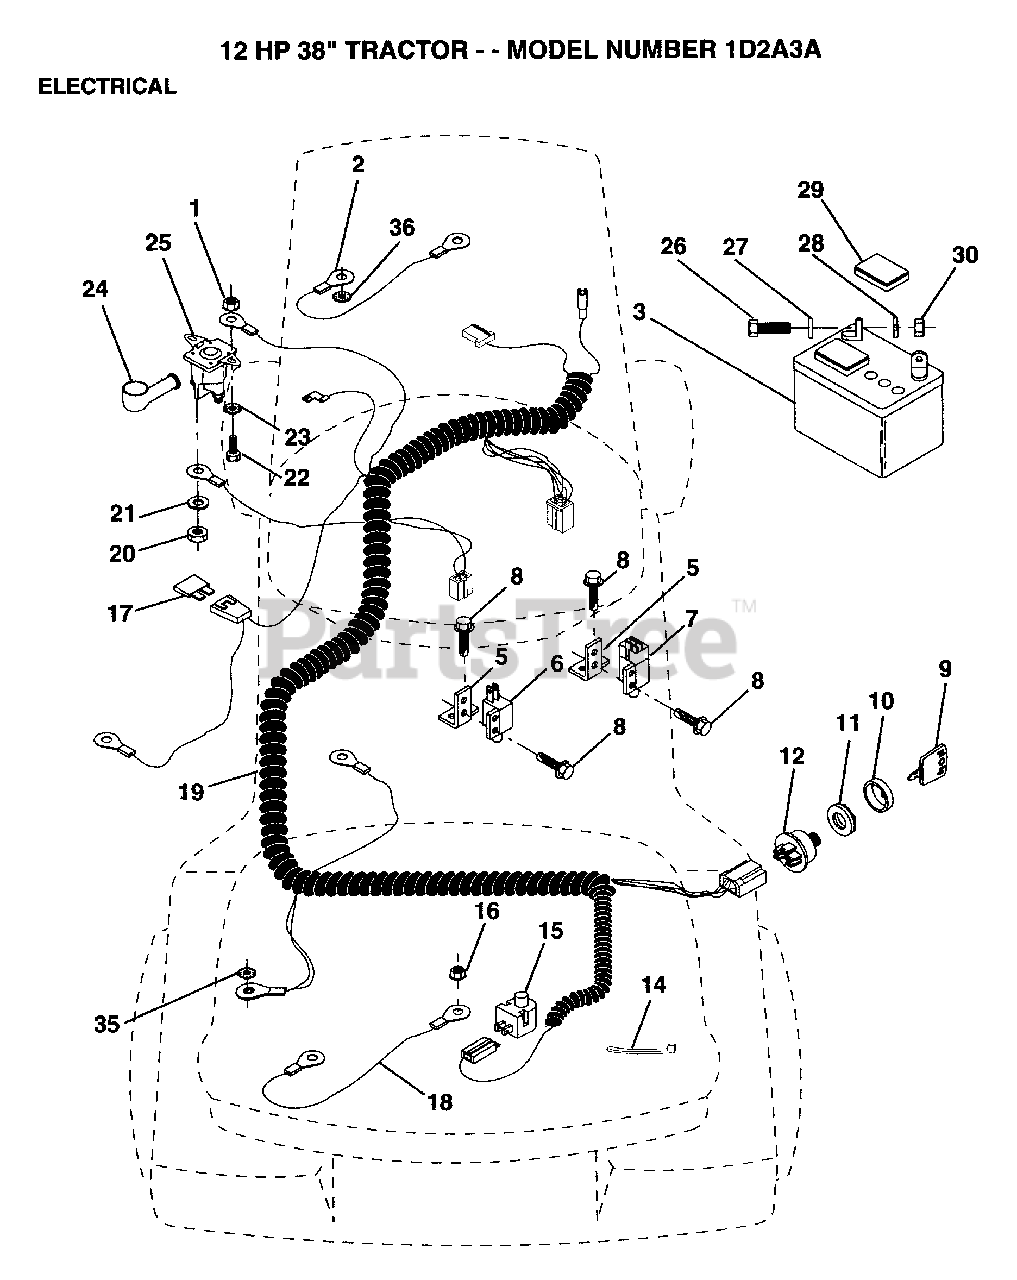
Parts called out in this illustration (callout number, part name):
1	NUT
2	CABLE ASM.
5	BRACKET LT
6	SWITCH-INTER. GT
7	SWITCH INTERLOCKT
8	SCREW
9	KEY
11	NUT IGNITION
14	WIRE TIE
15	SWITCH SEAT
17	FUSE HYT
18	CABLE ASSY
19	HARNESS.IGN
20	NUT
22	BOLT
26	BOLT LT
27	WASHER
28	LOCKWASHER
29	"CAP,BATTERY "
33	SWITCH LT
35	LOCKWASHER
36	LOCKWASHER
